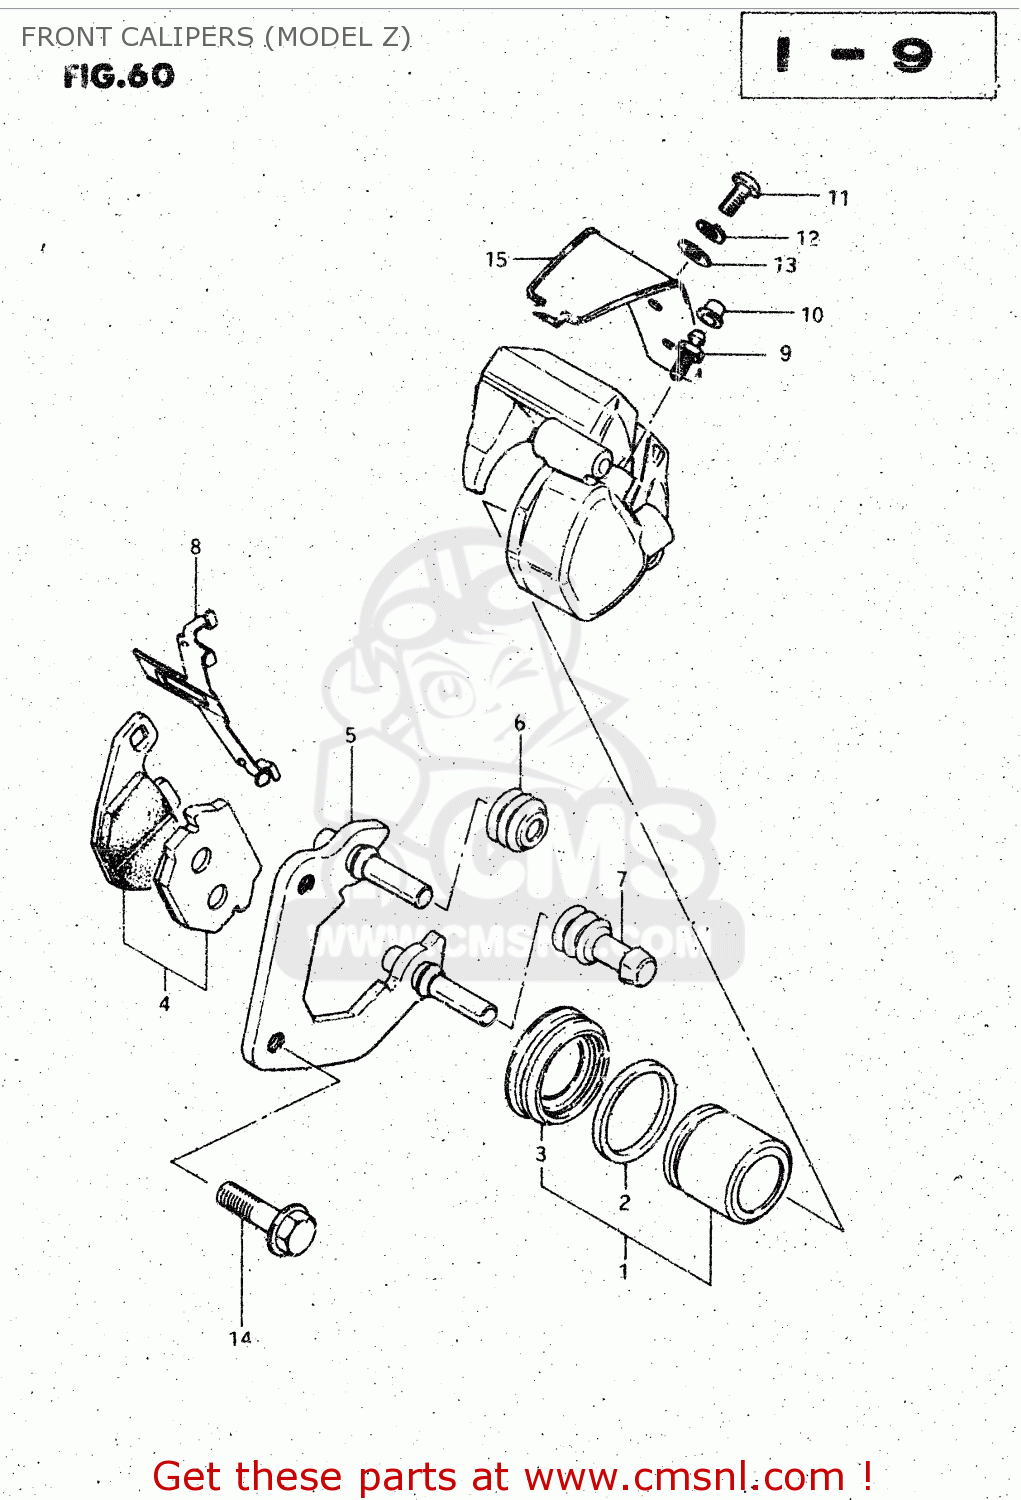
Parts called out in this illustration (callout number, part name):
1	PISTON SET
2	SEAL,PISTON
3	BOOT,PISTON
4	PAD SET,BRAKE (MCA)
5	CARRIER,L
6	BOOT,AXLE
7	INSULATOR,AXLE
8	SPRING,PAD
9	BLEEDER
10	CAP,BREATHER
11	SCREW
12	LOCK WASHER
13	WASHER
14	BOLT 8X30
15	COVER
